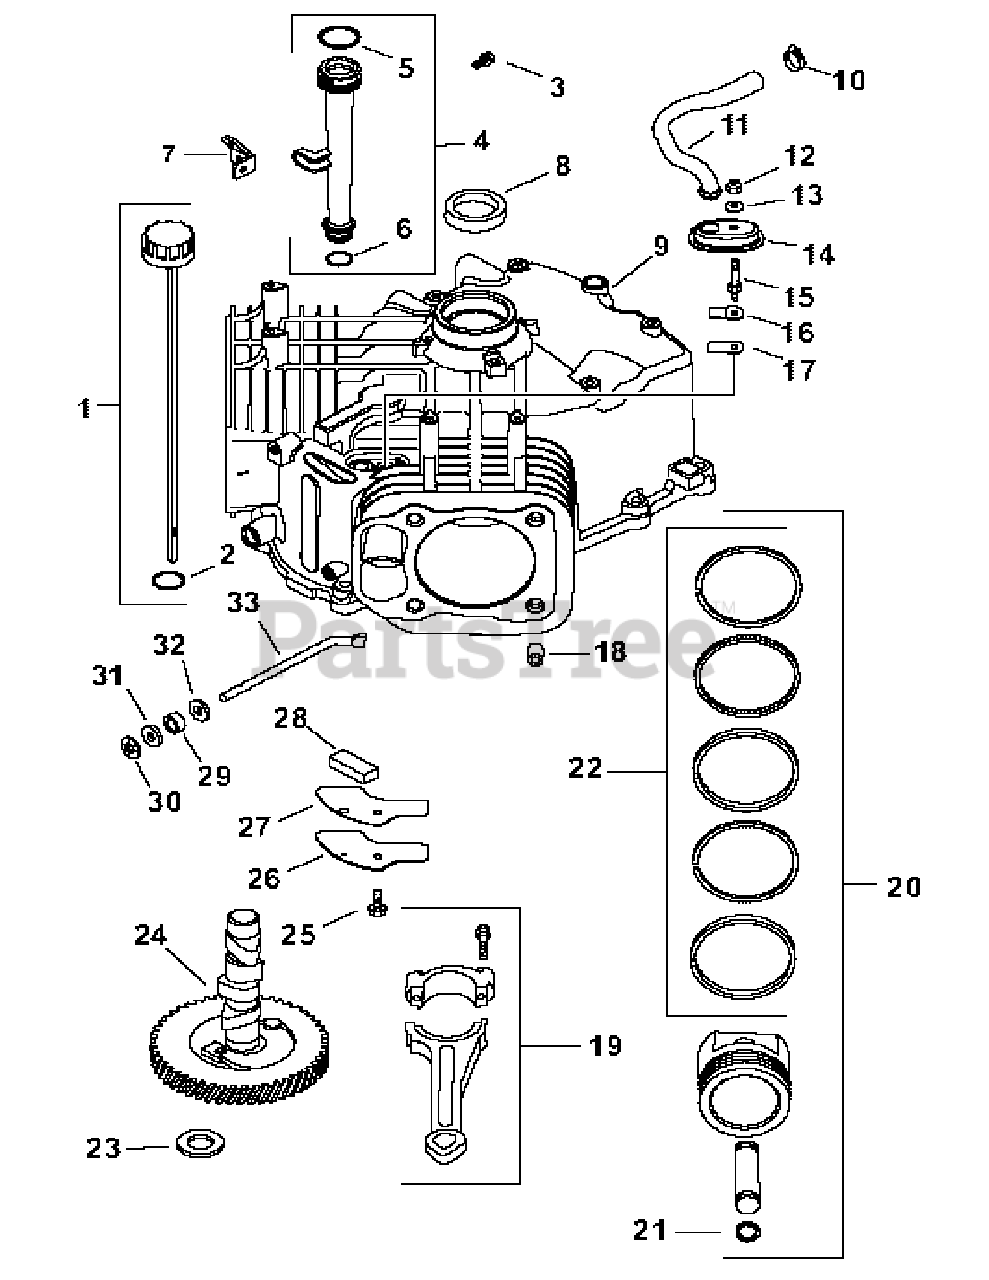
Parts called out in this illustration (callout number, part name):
1	Dipstick Kit
2	O-Ring
3	Hex Flange Screw
4	Oil Fill Tube
5	Upper Oil Fill Tube O-Ring
6	Lower Oil Fill Tube O-Ring
7	Oil Fill Tube Bracket
8	Oil Seal
9	Use Short Block
10	Hose Clamp
11	Breather Hose
13	Sealing Washer
14	Breather Housing
15	Breather Cover Stud
16	Breather Reed Retainer
17	Breather Reed
19	Connecting Rod (Std.)
20	Piston With Ring Set (Std.)
21	Piston Pin Retainer
22	Ring Set (Std.)
22	Ring Set (.25)
23	Camshaft Shim (White)
23	Camshaft Shim (Blue)
23	Camshaft Shim (Red)
23	Camshaft Shim (Yellow)
23	Camshaft Shim (Green)
23	SHIM-CAMSH
23	Camshaft Shim (Black)
25	Hex Flange Screw
26	Breather Cover
27	Breather Cover Gasket
28	Breather Filter
29	Governor Cross Shaft Seal
30	Retainer Ring
31	Plain Washer 8 mm
32	Flat Washer 1/4"
33	Governor Cross Shaft
